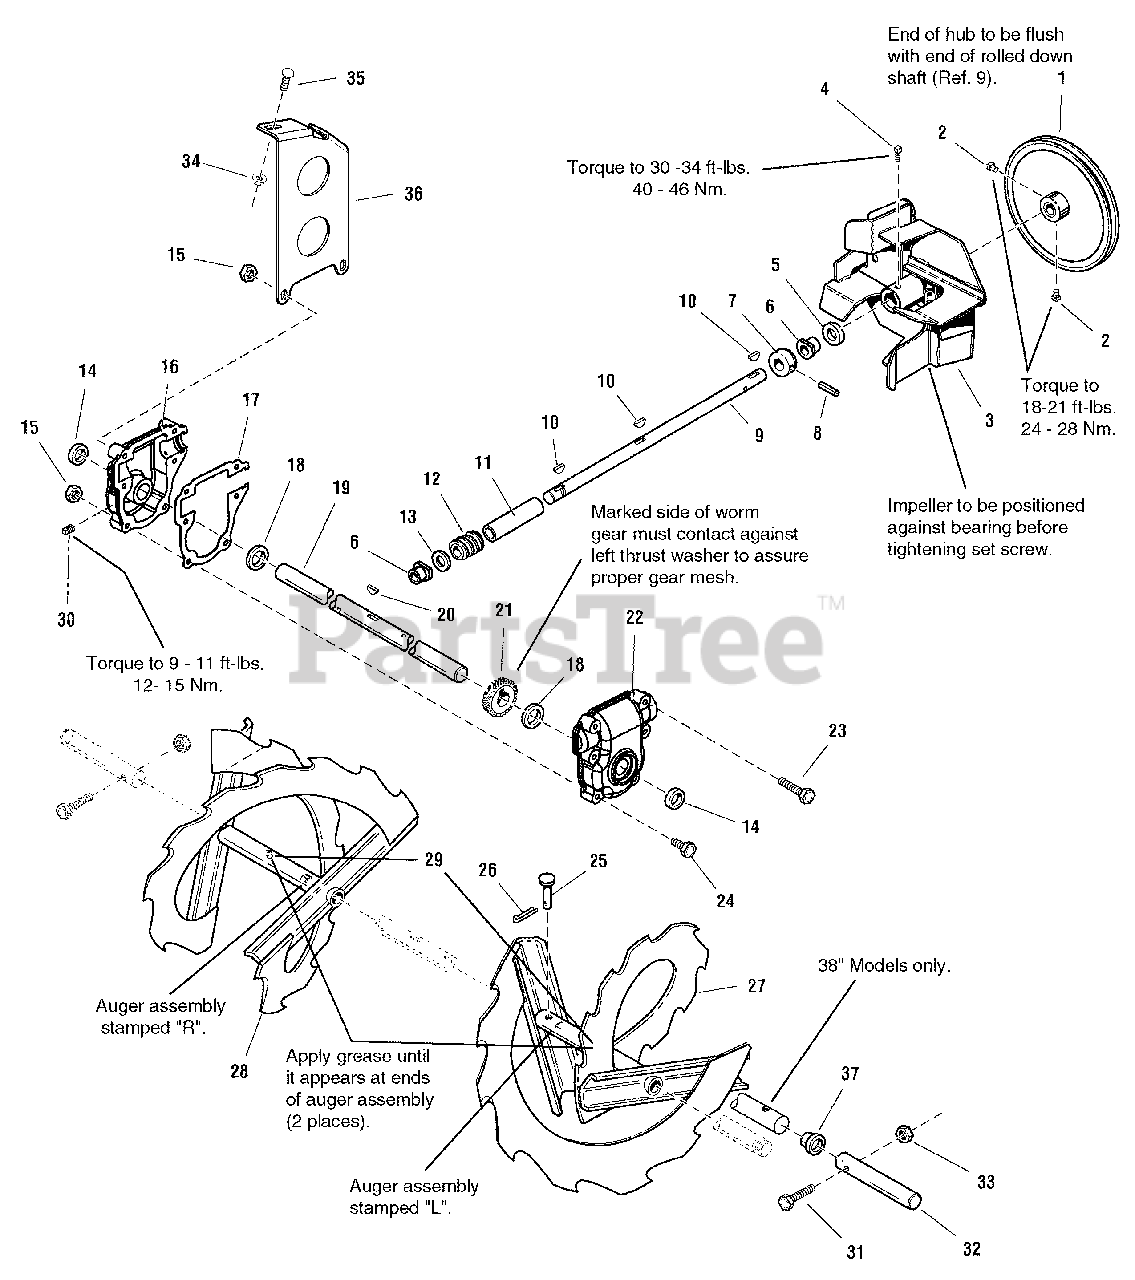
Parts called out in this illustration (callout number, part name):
1	PULLEY, w/Hub
2	SCREW, Set Square Head Cup Point, 5/16-18 x 1/2 G8
3	IMPELLER ASSEMBLY
4	SCREW, Set Square Head Cup Point, 3/8-16 x 1/2 G8
5	SEAL, Oil 1/4" Thick
6	BUSHING, 377/500 ID x 1-1/10 OD x 1-1/100 LG Powerdered Metal
7	COLLAR, Thrust 3/4 LG
8	PIN, Drive Lock Type A 3/16 x 1-1/2
9	SHAFT, Worm 18-1/10 LG
10	KEY, Woodruff, 47/250 x 5/8
11	TUBE, 9/10 OD 39/50 ID, 7-1/2 LG
12	GEAR, Worm 1-3/8 LG
13	WASHER, Thrust
14	SEAL, Oil, 1/4" Thick
15	NUT, Hex Flange, 1/4-20 Toplock Small (Uses Quantity of 6 on 28 adn 38 in. Models)
16	CASE, Gear R.H.
17	GASKET, Gear Case
18	WASHER, Thrust
19	SHAFT, 16 LG Auger 3 Holes
20	KEY, Woodruff 1/4 x 3/4
21	GEAR, Worm 7/8 LG
22	CASE, Gear L.H.
23	CAPSCREW, Hex Head, 1/4-20 x 2-1/2 G5 (Used on 32 and 38 in. Modles)
24	CAPSCREW, Hex Head, 1/4-20 x 2-1/4 G5 (Uses Quantity of 6 on 28 and 38 in. Models)
25	PIN, Flat Head Drilled
26	PIN, Cotter 47/50 x 3/4
27	AUGER ASSEMBLY, L.H. 9-1/2 LG (Used on 24 in. Models)
27	AUGER ASSEMBLY, L.H. 11-1/2 LG (Used on 28 in. Models)
27	AUGER ASSEMBLY, L.H. 13-1/2 LG (Used on 32 in. Models)
27	AUGER ASSEMBLY, L.H. 15-9/10 LG (without Burshing) (Used on 38 in. Models)
27	AUGER ASSEMBLY, L.H. 15-9/10 LG (Includes Ref. No. 37) (Used on 38 in. Models)
28	AUGER ASSEMBLY, R.H. 9-1/2 LG (Used on 24 in. Models)
28	AUGER ASSEMBLY, R.H. 11-1/2 LG (Used on 28 in. Models)
28	AUGER ASSEMBLY, R.H. 13-1/2 LG (Used on 32 in. Models)
28	AUGER ASSEMBLY, R.H. 15-9/10 LG (without Bushing) (Used on 38 in. Models)
28	AUGER ASSEMBLY, R.H. 15-9/10 LG (Includes Ref. No. 37) (Used on 38 in. Models)
29	FITTING, Lube 1/4 Drive, No Check Ball
30	FITTING, Pipe Plug, Square Head
31	CAPSCREW, Hex Head, 1/4-20 x 1-3/4 G5 (Used on 38 in. Models)
32	SHAFT, E-Coat, 5 LG (Used on 38 in. Models)
33	NUT, Hex Lock ESNA Light, 1/4-20NC-3B (Used on 38 in. Models)
34	NUT, Hex Flange, 5/16-18, Whiz Lock Small (Used on 32 and 38 in. Models)
35	CARRIAGE BOLT, 5/16-18 x 3/4 G5 (Used on 32 and 38 in. Models)
36	SUPPORT, Gear Box 10GA (Used on 38 in. Models)
37	BUSHING, Plastic (Used on 38 in. Models)
